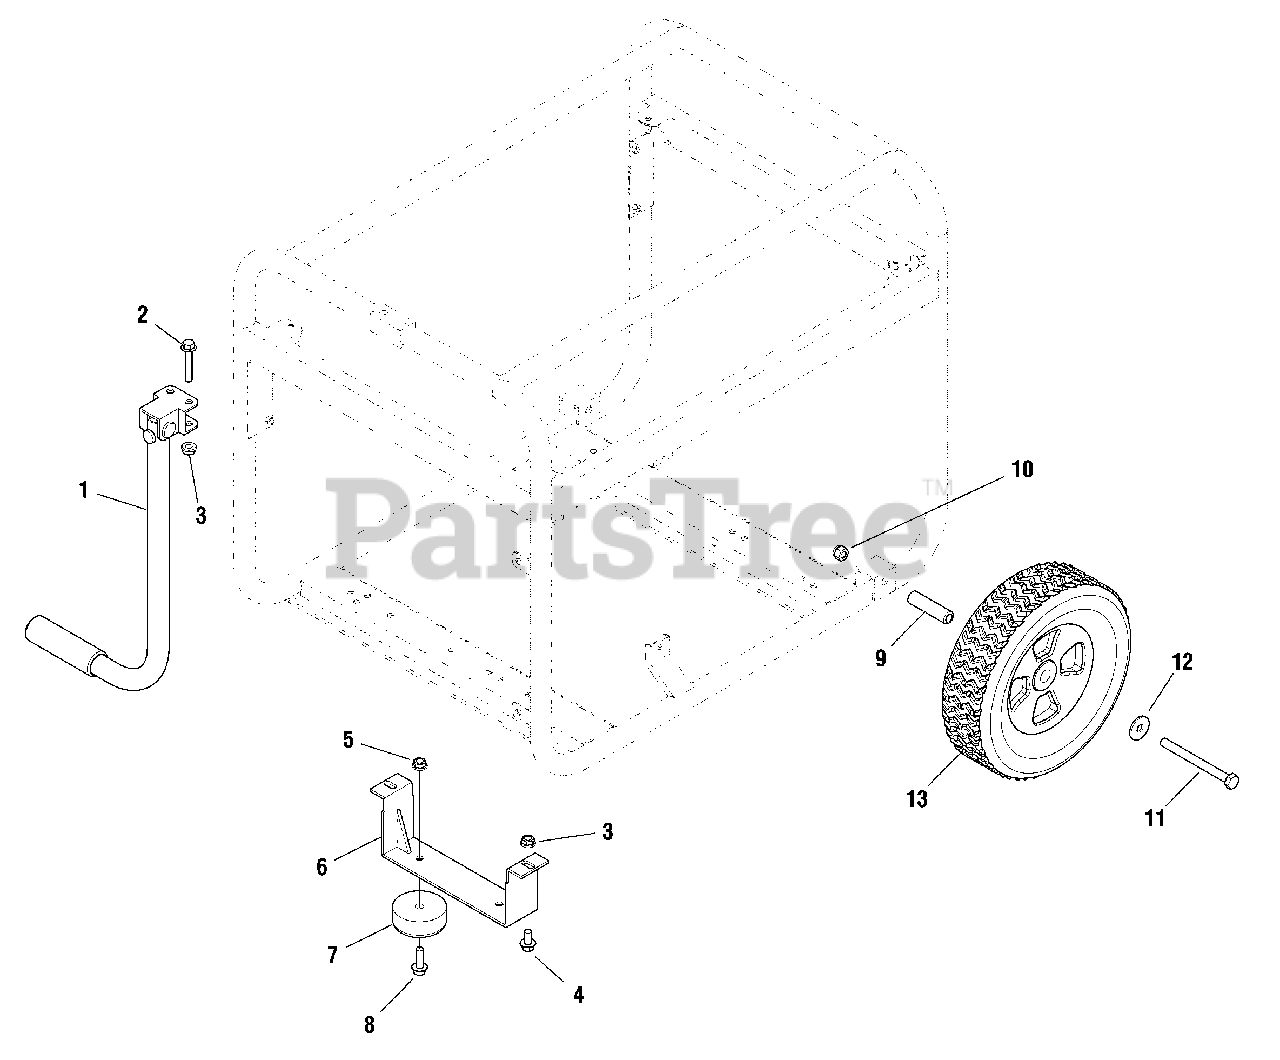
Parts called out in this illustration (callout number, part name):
2	* BOLT, M8 x 45
3	* NUT, Flange, M8
4	* BOLT, M8 x 16
5	* NUT, Flange, M6
8	* BOLT, M6 x 25
10	* NUT, Locking, M10
12	* WASHER, Flat, M10
